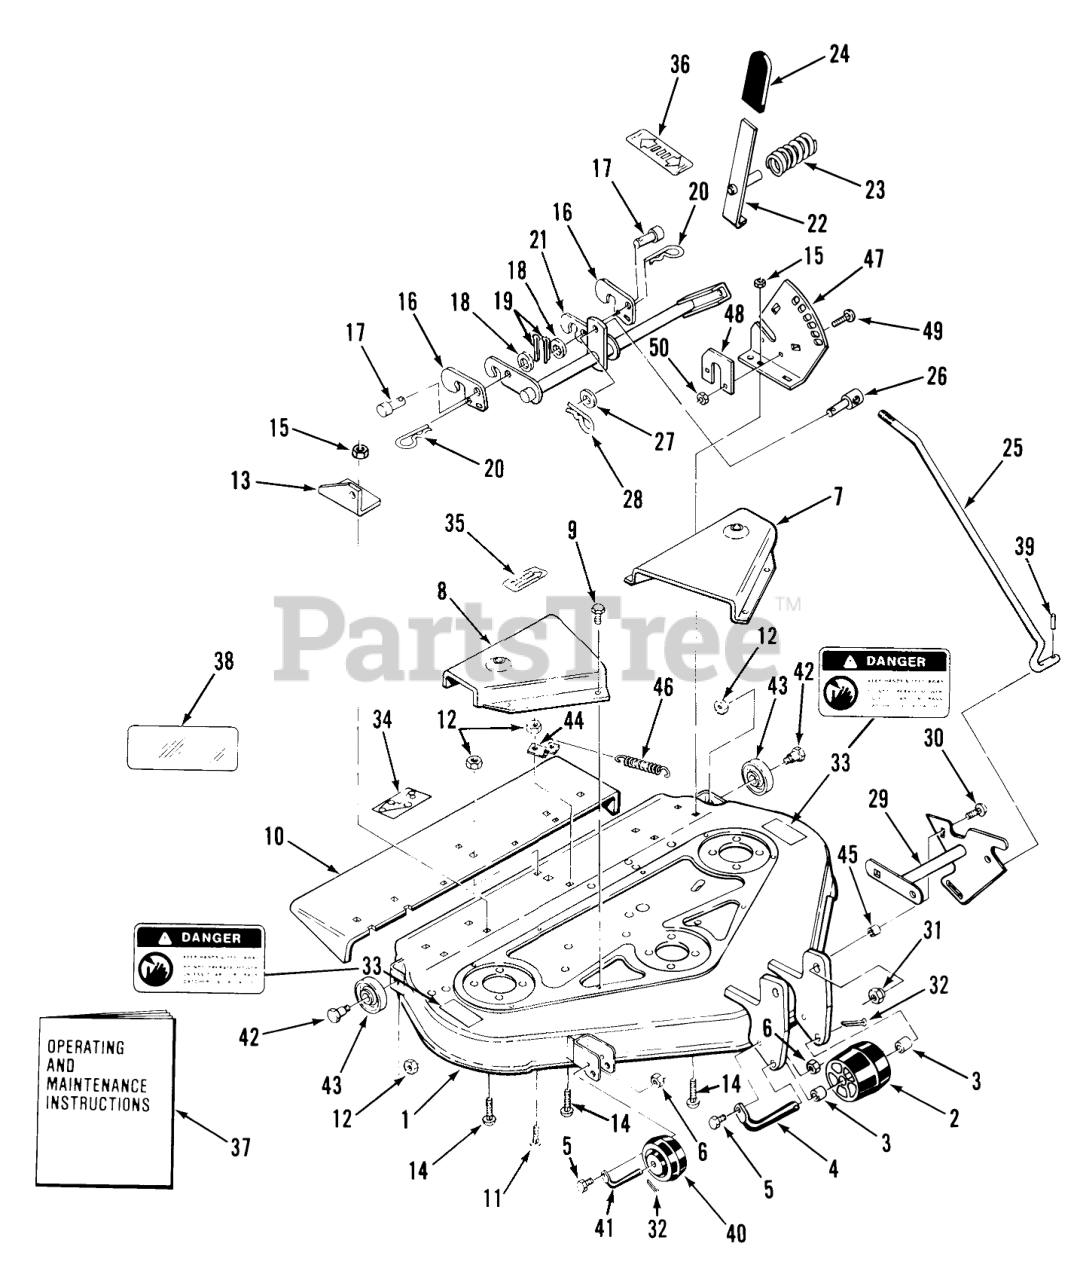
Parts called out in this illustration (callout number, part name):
1	ASS'Y-MOWER DECK R
2	Roller
3	SPACER-ROLLER B
4	SHAFT-ROLLER (FRONT)
5	Bolt
6	Nut
7	DECAL REAR HOOD
8	SHIELD-BELT RH R
9	Bolt
10	Chute Extension
11	Bolt-Carriage
12	NUT
13	BRACKET-HT ADJ R
14	Bolt
15	NUT
16	Latch
18	Washer
19	Cotter Pin
20	Hairpin Cotter
21	WELDMENT-HT ADJ S R
22	LEVER ASSY
23	SPRING-COMPRESSION
25	ASS'Y-HEIGHT ADJ R
26	STUD-TRUNION
27	Washer
28	Hairpin Cotter
29	ASM-FRONT LIFT R
30	Bolt-Carriage
31	LOCKNUT-FLANGE
32	Cotter Pin
33	Danger Decal
34	DECAL-BELT INSTALLAT
35	DECAL-BELT ADJUST
36	DECAL-HOC
37	Operating and Maintenance Instructions
38	DECAL-OVERLAY
39	SPIROL PIN
40	ROLLER
41	SHAFT-ROLLER
42	BOLT-SHOULDER
43	WHEEL-GAGE
44	ANCHOR-SPRING R
45	SPACER
46	SPRING-EXTENSION
47	Quadrant
48	PLATE-RETAINING R
49	Bolt
50	Nut
